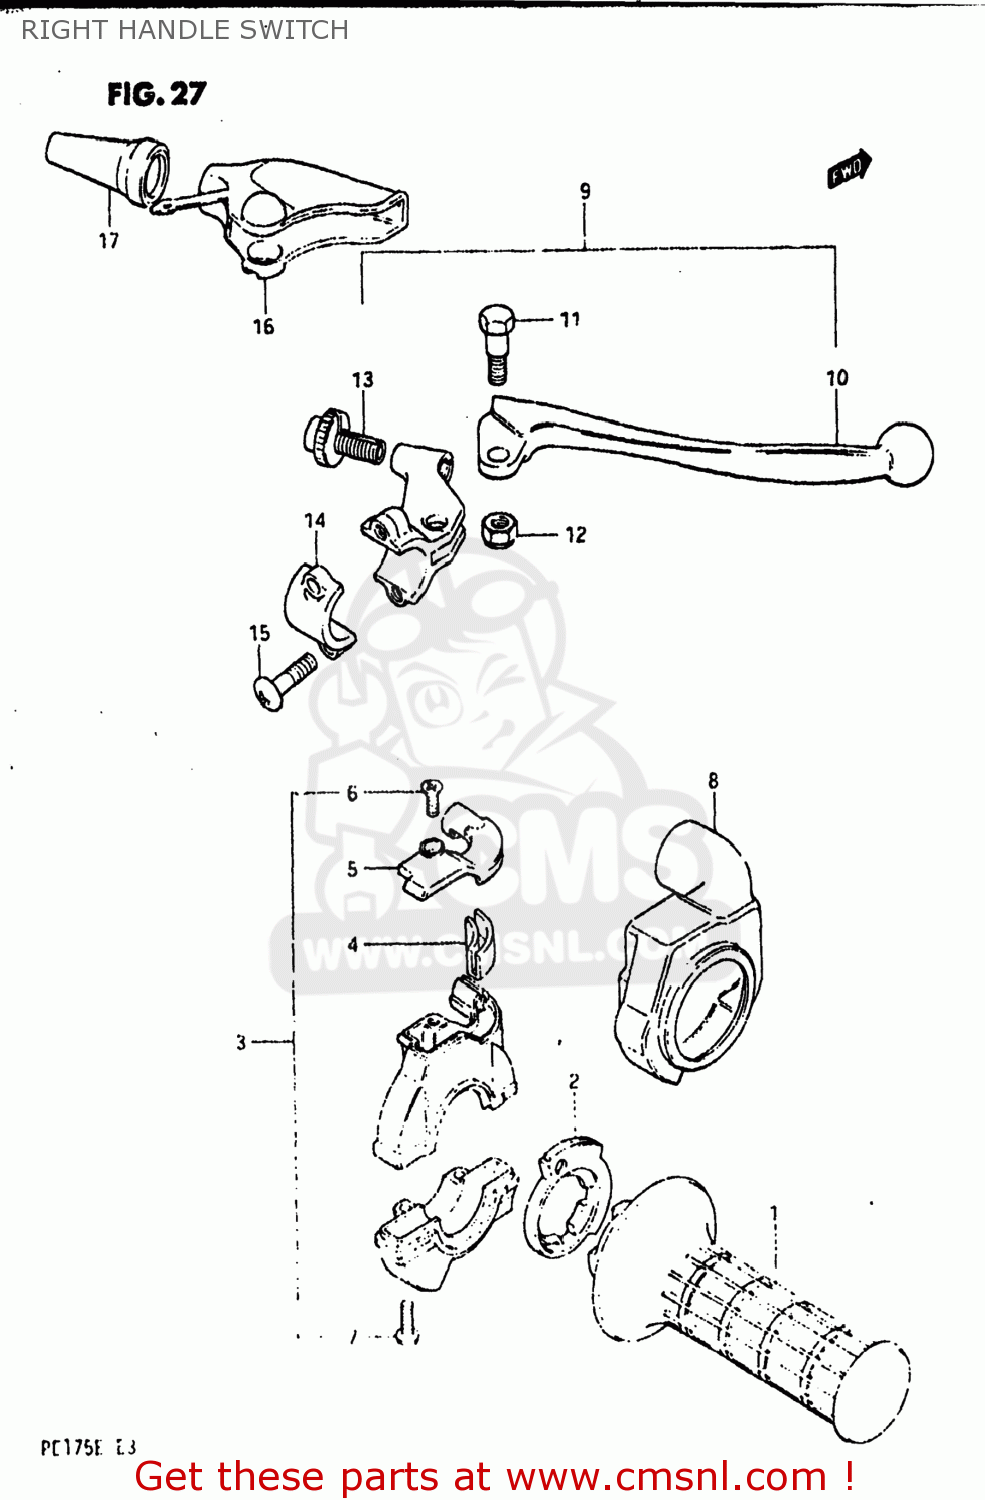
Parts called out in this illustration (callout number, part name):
1	GRIP,THROTTLE
2	ROTOR,THROTTLE GRIP
3	CASE ASSEMBLY,THROTTLE
4	GUIDE PIECE,THROTTLE
5	COVER,THROTTLE CASE
6	SCREW
7	SCREW
8	COVER,THROTTLE CASE
9	LEVER ASSEMBLY,BRAKE
10	LEVER,BRAKE
11	BOLT,LEVER
12	NUT 6MM
13	ADJUSTER,CABLE
14	BRACKET,LEVER
15	SCREW
16	COVER,BRAKE LEVER
17	BOOT,CLUTCH CABLE
